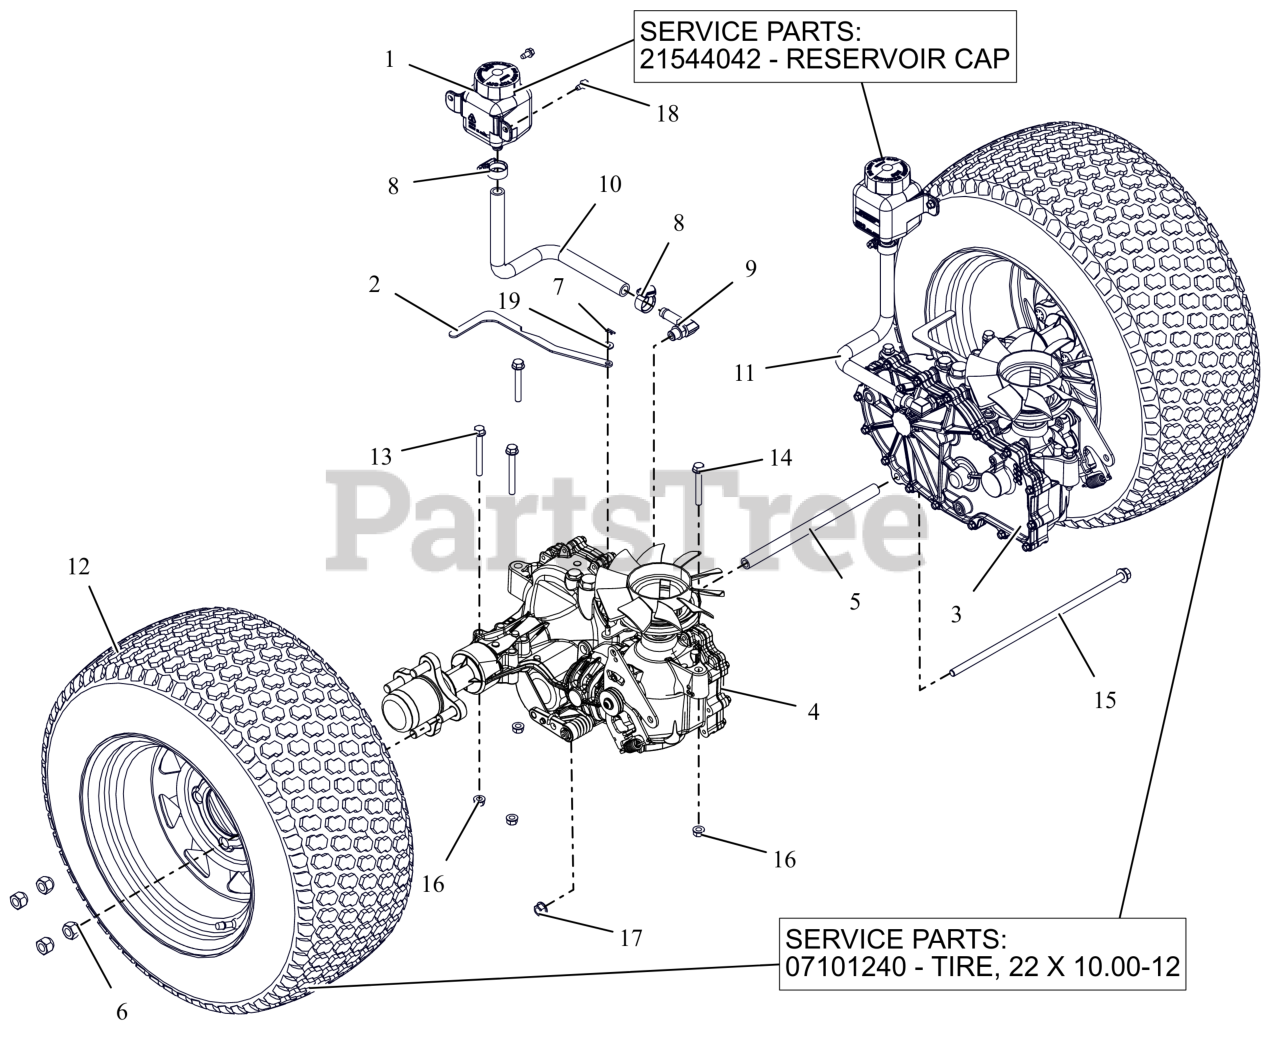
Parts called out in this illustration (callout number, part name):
1	TANK, EXPANSION
1	CAP, HYDRO RESERVOIR REPLAC.
2	BRKT, VALVE DUM
3	TRANSAXLE, ZT3200 LH
4	TRANSAXLE, RH ZT3200
5	SPCR, TRANSAXLE .406 ID X .630 OD X 9.95LG (BLACK)
6	NUT, WHEEL .50-20 ZCC
7	PIN, HAIR #225 .072X1.09
8	CLAMP,.88 DIA. HOSE
9	FITTING, HYD (90 DEG)
10	HOSE, FORMED EXPANSION -HD RH
11	HOSE, FORMED EXPANSION -HD LH
12	ASM, WHL/TIRE 22X10.00-12 K500
12	TIRE, 22X10.00-12
13	BLT,HEX-FLG .31-18X2.75 G5 ZCC
14	BLT,HEX-FLG .31-18X2.25 G5 ZCC
15	BLT, HEX-FLG 0.375-16X13 GR5 ZC120
16	NUT,LK-CTR-FLG .31-18 GF ZCC
17	NUT-LK-CTR-FLG .375-16 GF ZCC
18	SCR-TAP .25-20X.50 HWH ZCC
19	WSHR,FLT .281X.625X.065 ZCC
